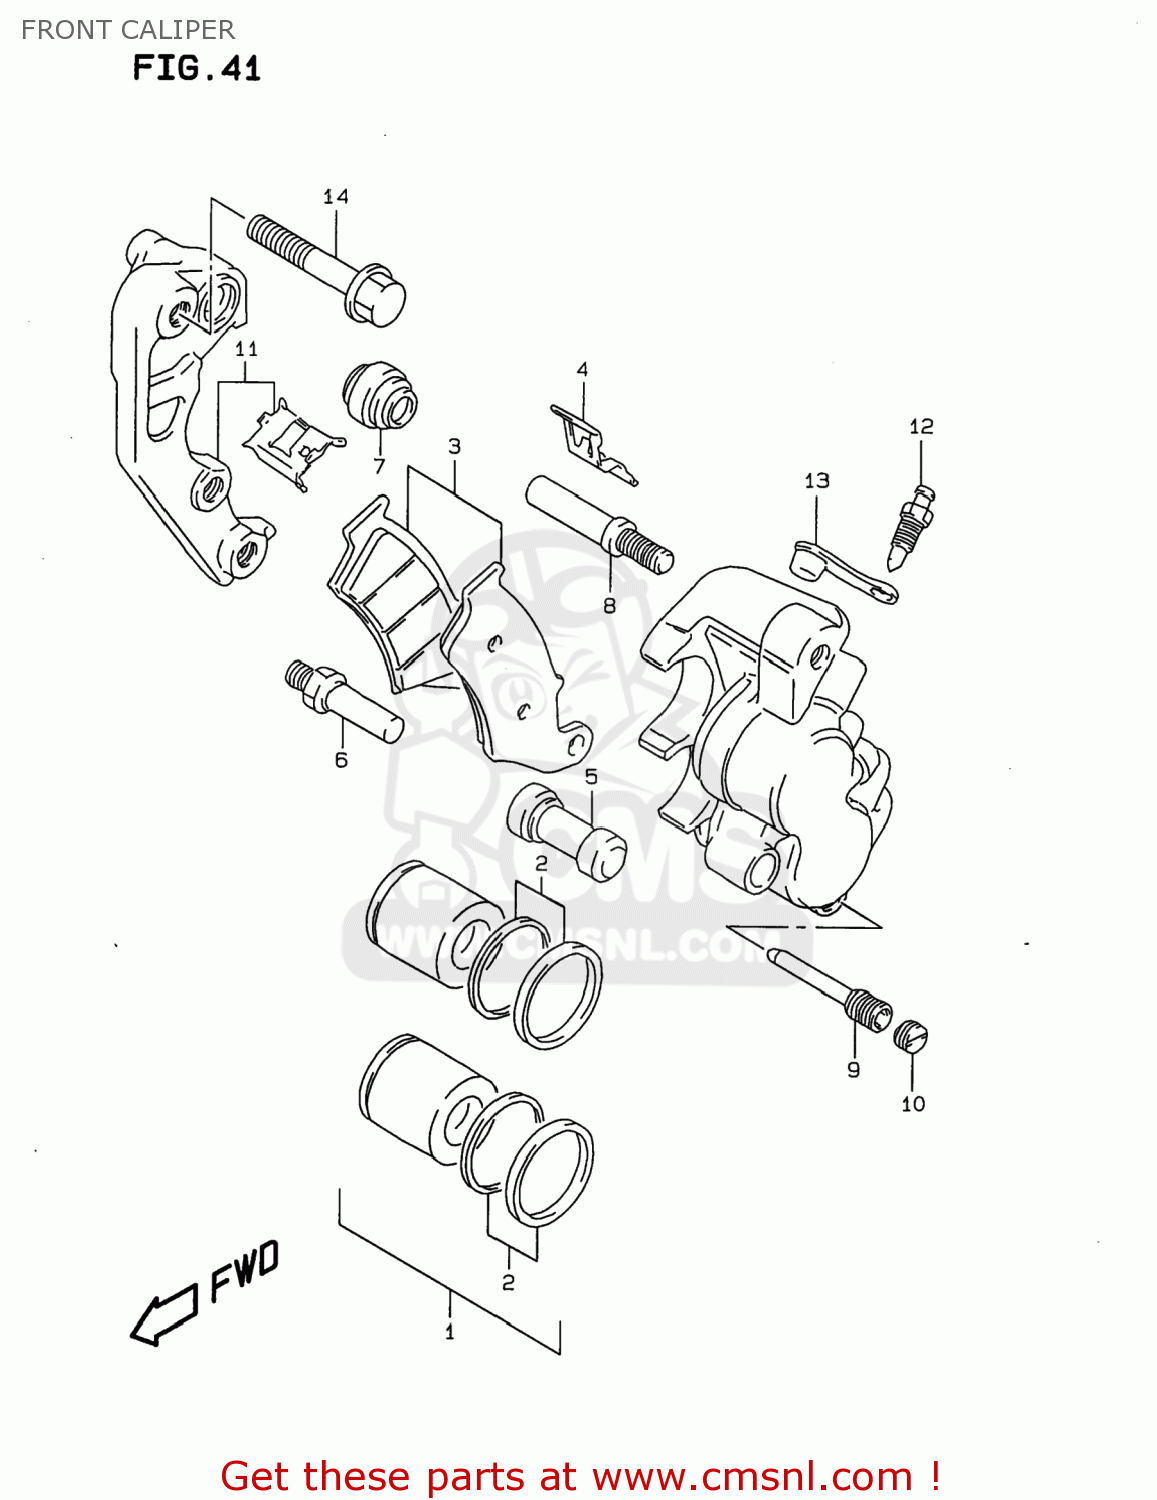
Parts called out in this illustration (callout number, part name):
1	PISTON SET
2	SEAL SET,PISTON
3	PAD SET (NAS)
4	SPRING,PAD
5	BOOT
6	BOLT
7	BOOT
8	PIN
9	PIN,HANGER
10	PLUG,PIN
11	BRACKET
12	BLEEDER
13	CAP,BLEEDER
14	BOLT(8X40)
